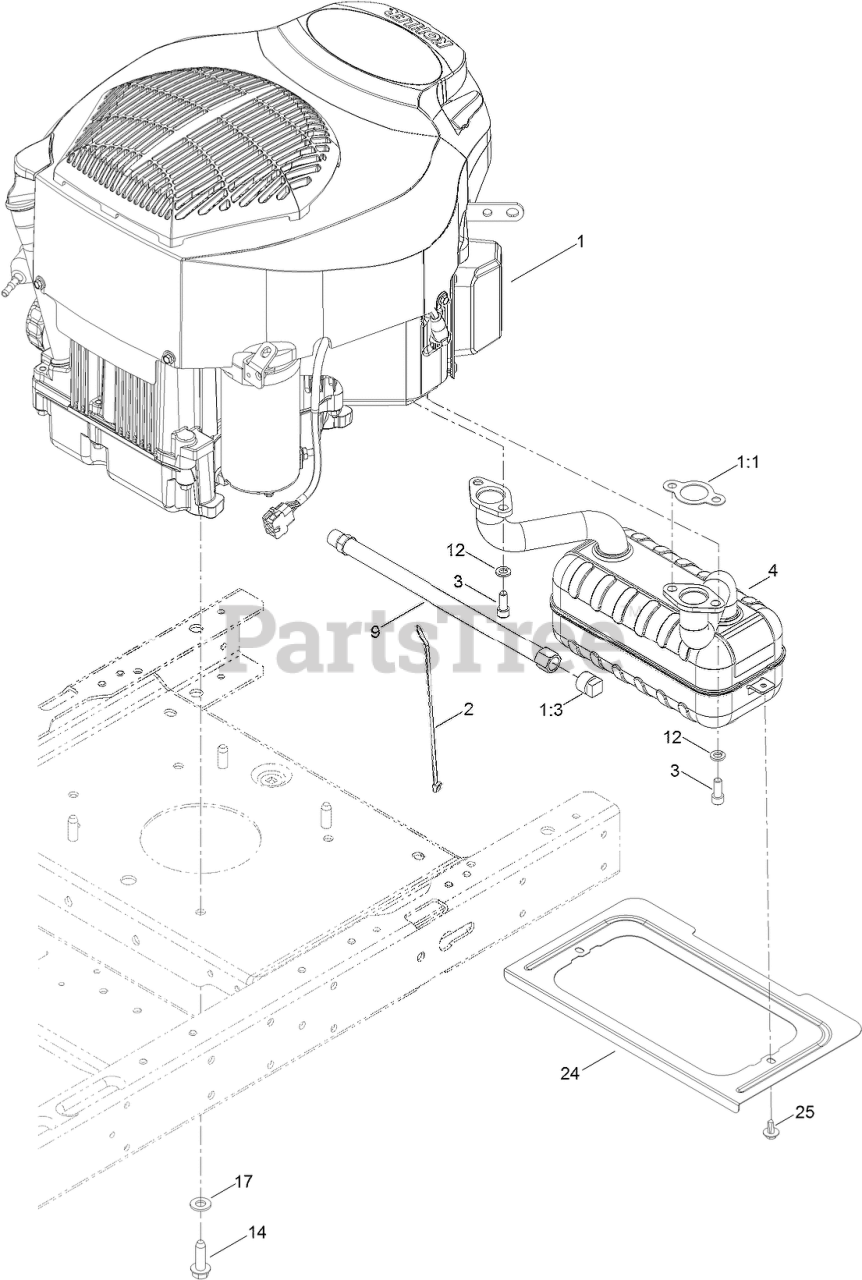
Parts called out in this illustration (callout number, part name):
1	ENGINE-KOHLER 24HP 7000 SERIES AUTOCHOKE
1:1	GASKET-EXHAUST
1:3	PLUG-PIPE, SQH
2	TIE-CABLE
3	SCREW-HSH
4	MUFFLER-KOHLER
9	HOSE-DRAIN, OIL
12	WASHER-LOCK
14	SCREW-TAPTITE
17	WASHER-FLAT
24	SHIELD-HEAT
25	SCREW-HHFTF
